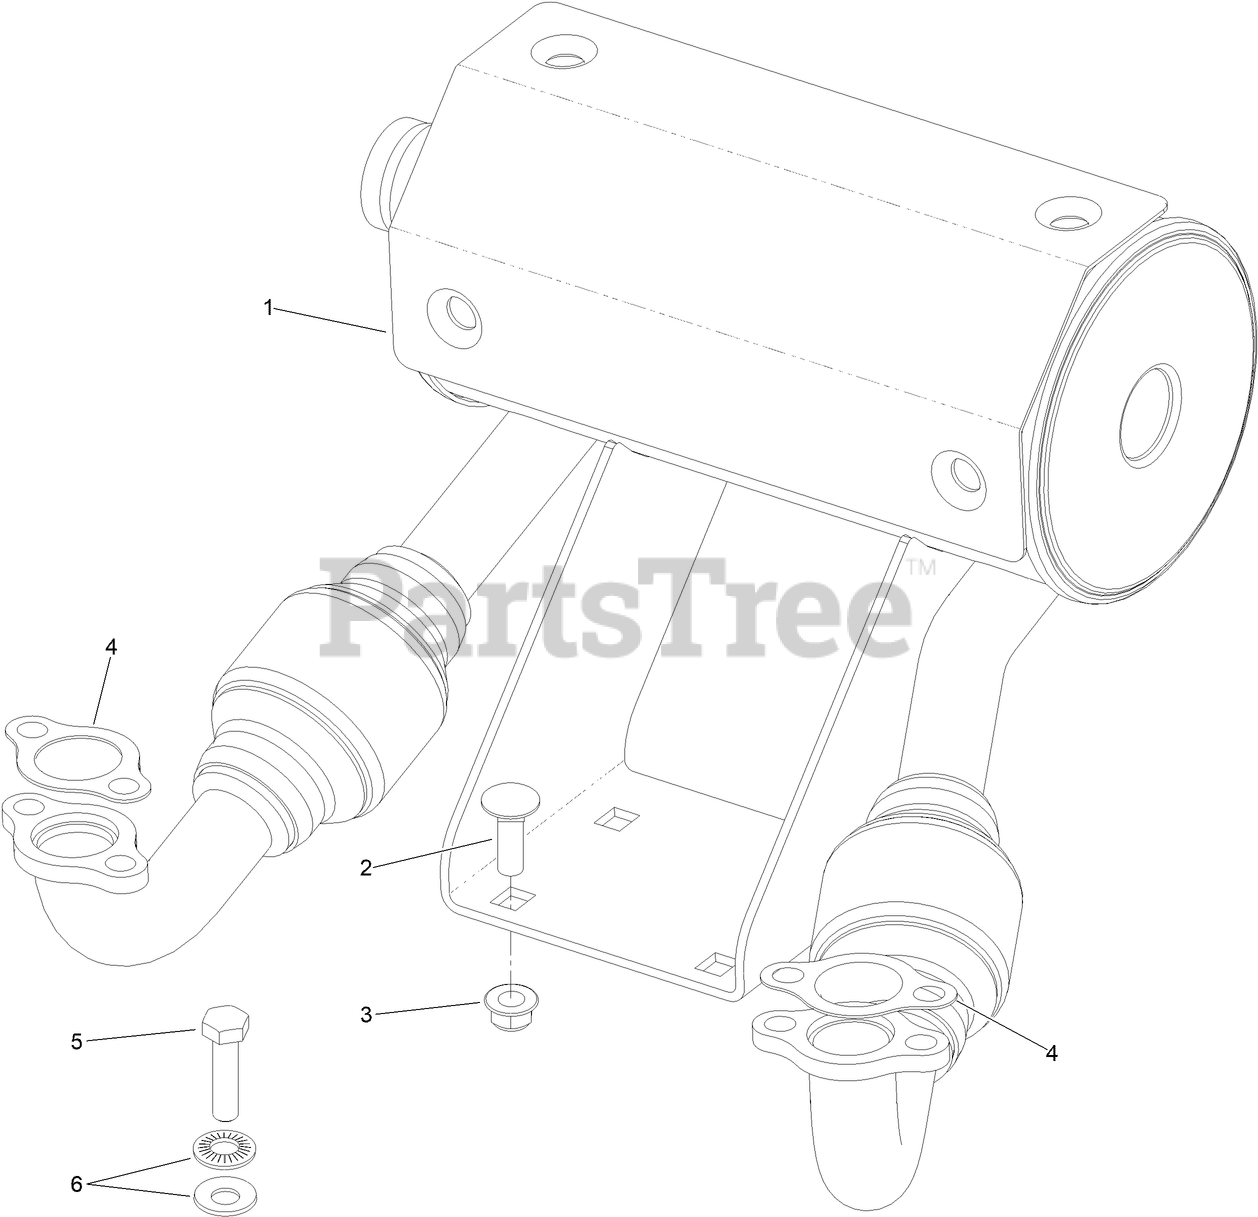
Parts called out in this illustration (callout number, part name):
1	MUFFLER, FX850/801 FLEX
2	SCREW-CARR
3	NUT-HF, NI
4	GASKET-EXHAUST
5	SCREW-HH, W/LOCTITE
6	WASHER-SPRING
